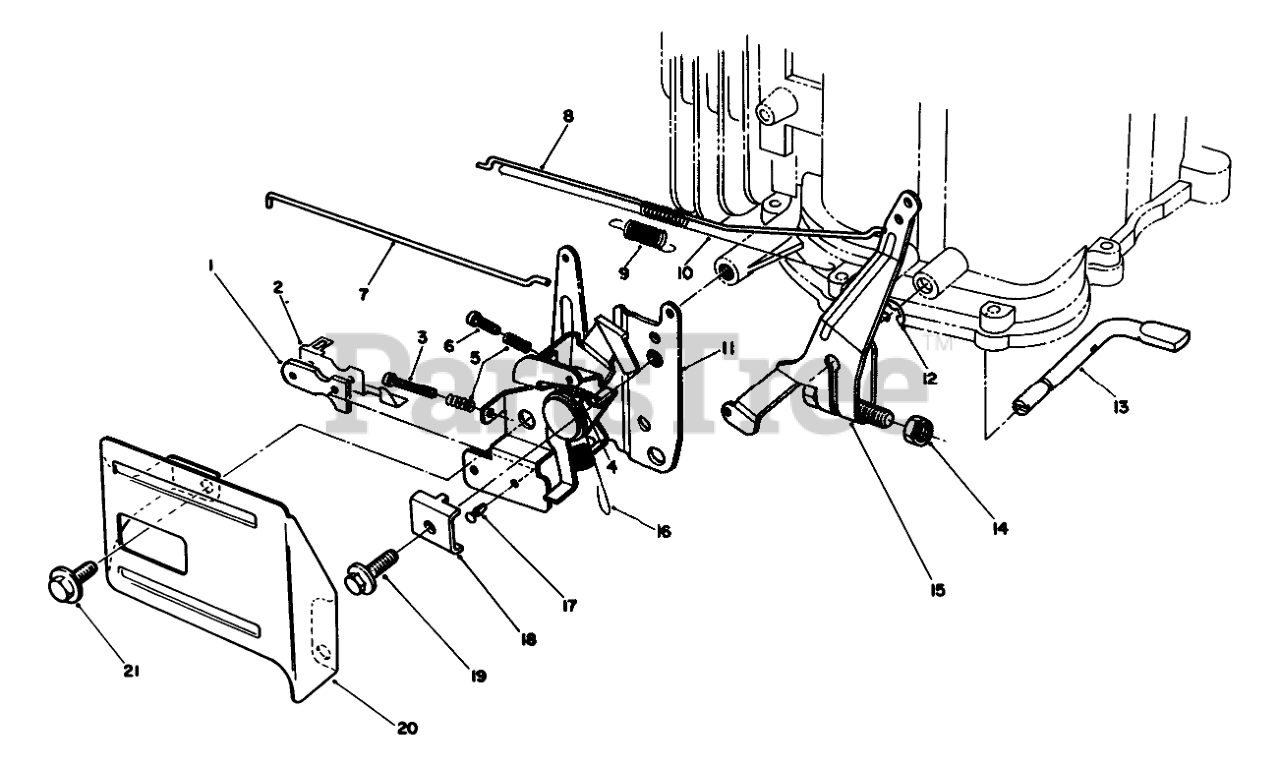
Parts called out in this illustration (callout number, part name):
1	INSULATOR-KILL SWITCH
2	TERMINAL-KILL SWITCH
3	SCREW
4	SPRING
5	SPRING
6	SCREW
7	Rod-Choke
8	Rod-Carburetor
9	SPRING
10	SPRING
11	THROTTLE
12	E-RING
13	SHAFT
14	Nut
15	ARM ASM
16	SPRING
17	RIVET
18	CLAMP-CABLE
20	THROTTLE GUARD
